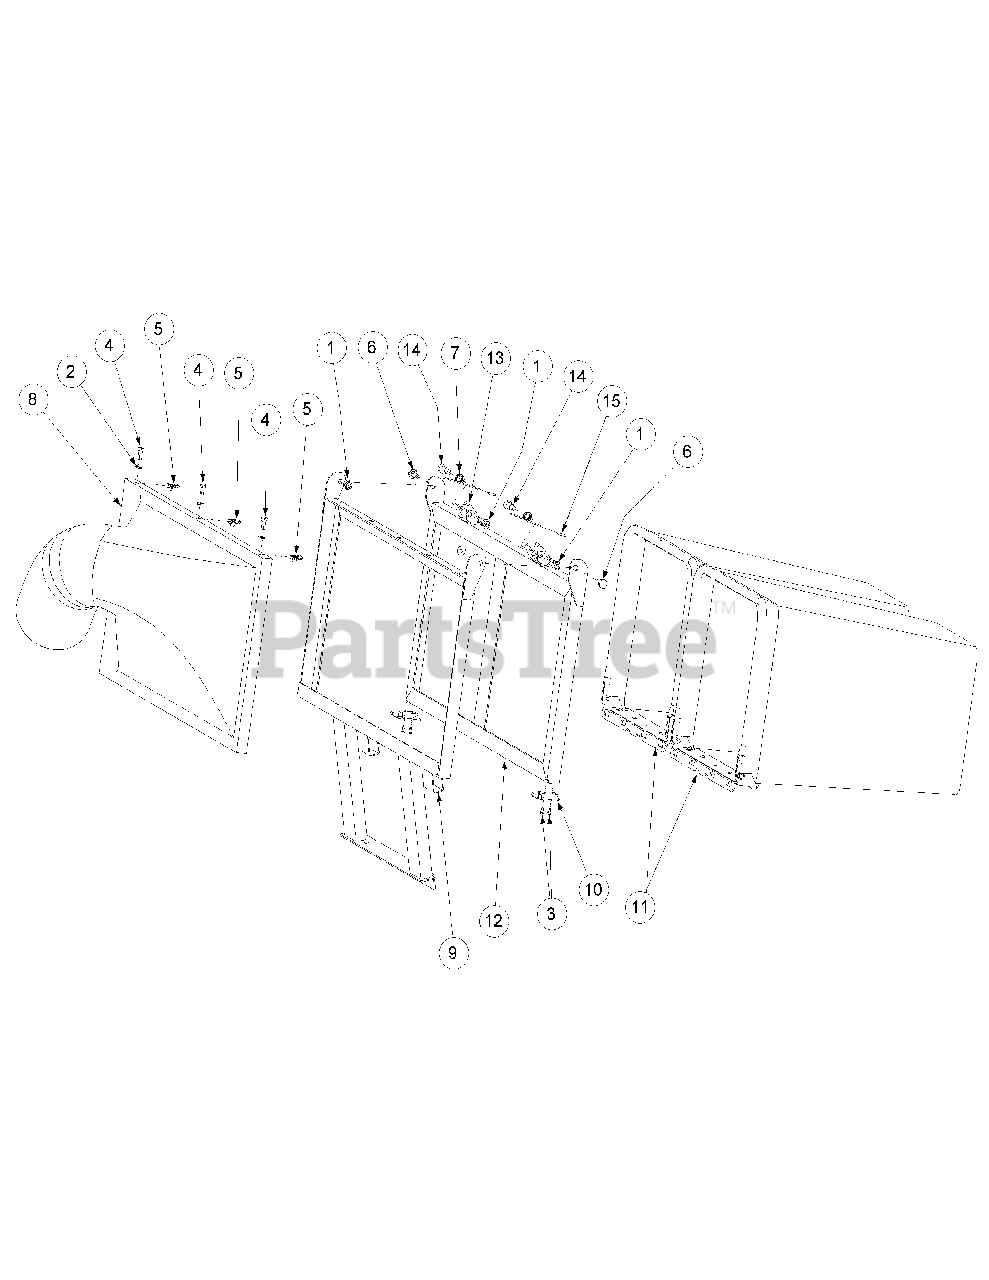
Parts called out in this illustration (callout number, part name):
1	Flange Lock Hex Nut, 3/8-16
2	Lock Washer, 5/16
3	Screw, #8-32 x 0.375
4	Hex Cap Screw, 5/16-18 x 1.00
5	U-Nut, 5/16-18
6	Shoulder Screw, .50 OD x 0.27
7	Spring
8	MCS Back Baffle
9	MCS Main Frame Weldment
10	Draw Latch
11	Double Bagger Assembly
12	Door Frame Weldment
13	Rear Bagger Latch
14	Shoulder Bolt, 1/2 x 3/4, 3/8-16
15	Cap, Spring
